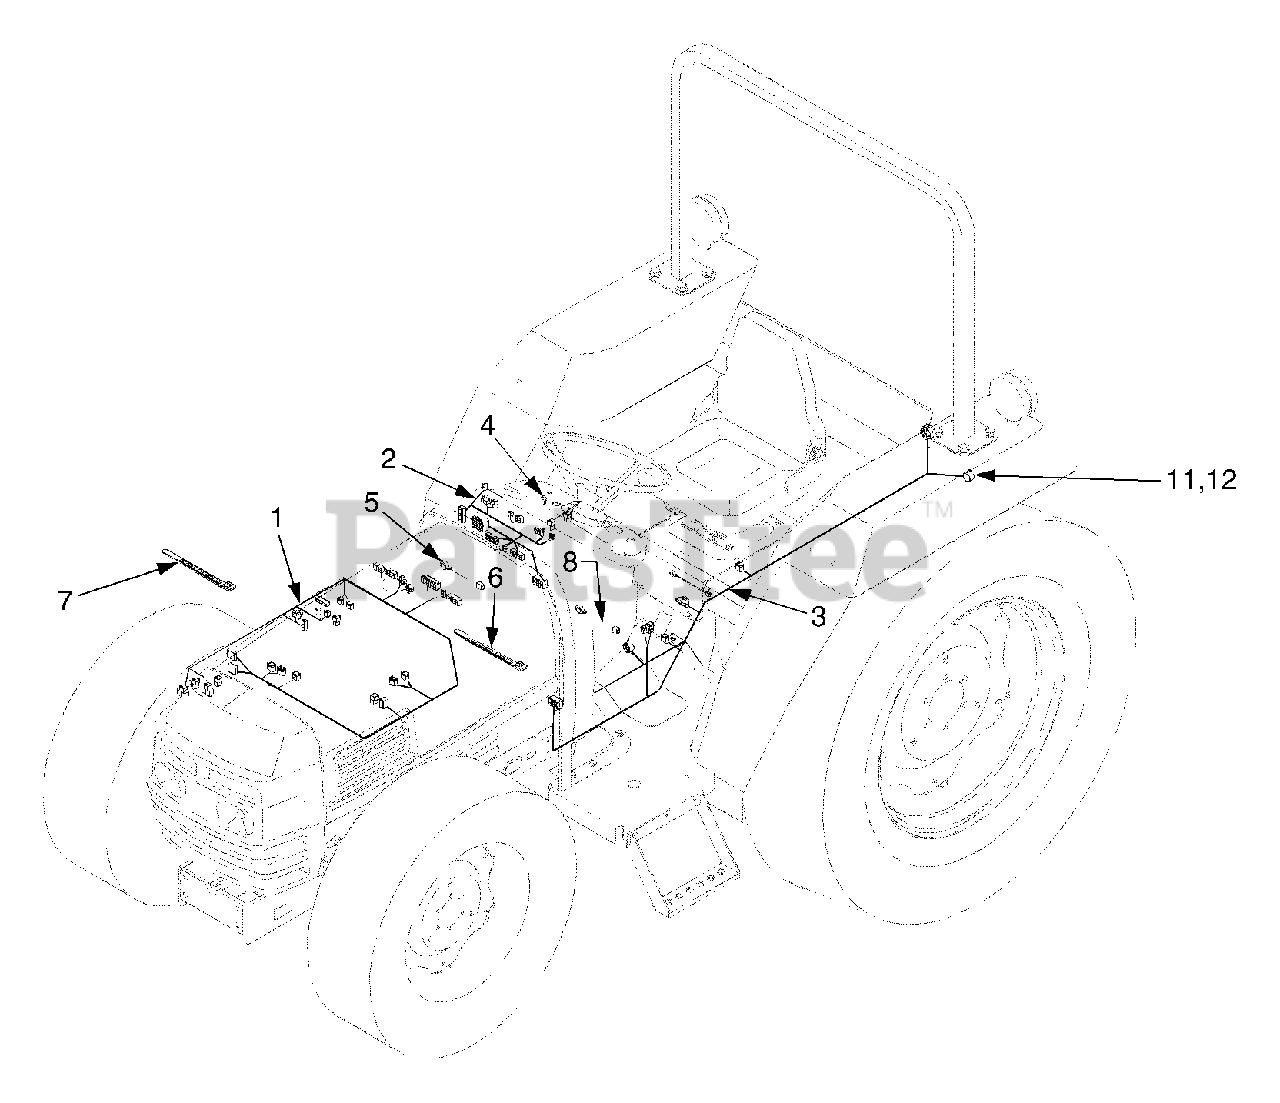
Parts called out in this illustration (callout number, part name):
1	Bonnet Wire Harness Ass'y
2	Panel Wire Harness Ass'y
3	Fender Wire Harness Ass'y
4	Wire Harness 2
5	Wire Harness 3
8	Wire Harness 2
11	Wire, Connection(LH)
12	Wire, Connection(RH)
